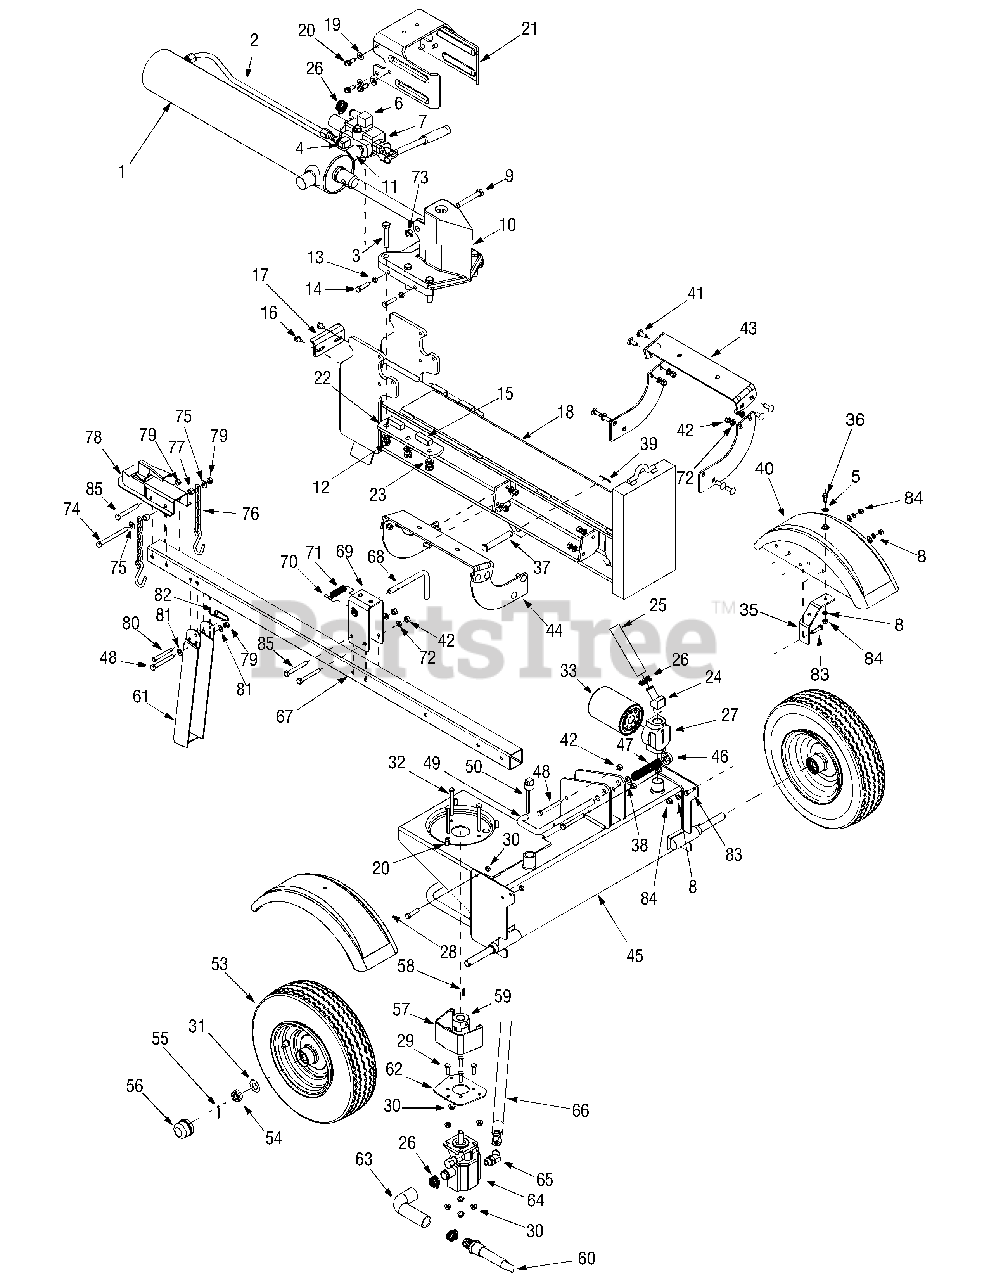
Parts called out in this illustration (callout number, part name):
1	Hydraulic Cylinder
1	Seal Kit 4.5" for Fisher Cylinder 718-0769
1	Kit Seal 4.5" for XINGHUI cylinder 718-0769A
1	Kit Seal 4.5" for ENERGY cylinder 718-0769A
2	Hydraulic Tube
3	Hex Cap Screw, 1/2-20 x 2.75
4	90 Degree Solid Adapter
5	Flat Washer, .434 x .880 x .062
6	Return Elbow
8	Lock Washer, 5/16
9	Hex Cap Screw, 1/2-13 x 3.25
10	Wedge Assembly
11	Nipple Pipe, 1/2-14
12	Lock Nut, 1/2-20
13	Hex Jam Nut, 3/8-24
14	Hex Cap Screw, 3/8-24 x 1.5
16	LD Screw, 5/16-18 x.75
19	Flat Washer, .406 ID x.875 OD
20	Hex Washer Screw, 3/8-16 x 1.0
23	Lock Washer, 1/2
24	Adapter, 3/4-14
25	Return Hose, 3/4" ID x 44"
26	Hose Clamp, 5/8"
27	Filter Housing
28	Hex Screw, 5/16-18 x .75
29	Hex Screw, 5/16-18 x 1.0
30	Hex Flange Nut, Nylon, 5/16-18
31	Flat Washer.760 ID x.500 OD
32	Hex Bolt 5/16-18 x 3.25"
33	Oil Filter
36	Hex Screw, 5/16-18 x .875
37	Clevis Pin
38	Flat Washer.635 ID x.93 OD
39	Cotter Pin
40	Fender, Red
40	Fender, Black
41	Carriage Bolt, 3/8-16 x 1.0
42	Hex Flange Lock Nut, 3/8-16
46	Push Cap
47	Compression Spring
48	Hex Bolt, 3/8-16 x 3.25"
49	Lock Rod
50	Vented Dipstick
51	Hex Screw, 5/16-24 x 3.25
53	Wheel Assembly
54	Slotted Nut, 3/4-16
55	Cotter Pin
56	Hub Cap
57	Coupling Shield
58	Square Key, 3/16" x.75
59	Flexible Coupling
60	Inlet Filter
64	Gear Pump
65	45° Elbow
66	High Pressure Hydraulic Hose
68	Tongue Latch Rod
70	Spiral Pin
71	Compression Spring
72	L-Washer, 3/8"
73	Hex Lock Nut, 1/2-13
74	Hex Cap Screw, 3/8-16 x 4.25
75	Flat Washer, .385 ID x.870 OD
76	Chain
77	Spacer, .375 ID x.625 OD
78	Hitch Coupler
79	Hex Lock Nut, 3/8-16
80	Clevis Pin
81	Flat Washer, .375 ID x.738 OD
82	Spring Pin
83	Hex Screw, 5/16-18 x .875
84	Hex Nut, 5/16-18
85	Hex Bolt, 3/8-16 x 3"
